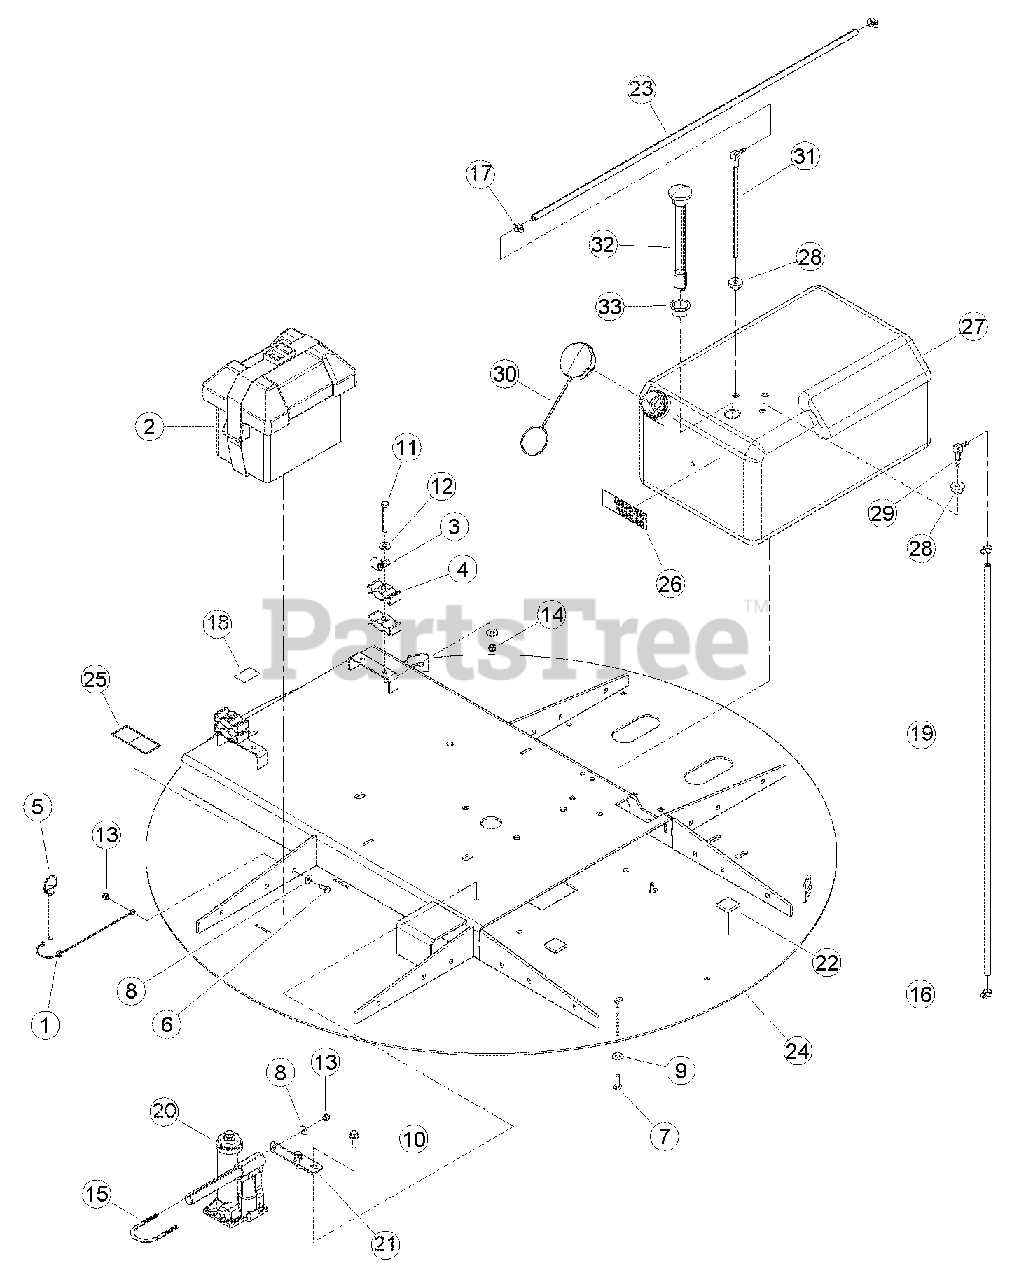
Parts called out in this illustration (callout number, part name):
1	LANYARD, NYLON
2	BOX, SMALL BATTERY
3	CLAMP, 9/16" COATED
4	CLAMP, PLASTIC HOSE
5	PIN, 3/8 HITCH
6	BOLT, 1/4 X 3/4 HEX HD GR5 ZP
7	BOLT, 3/8 X 3/4 HEX HD GR5 ZP
8	WASHER, 1/4 FLAT ZP
9	WASHER, 3/8 FLAT ZP
10	SCREW, 3/8-16 X 1 LG THD CUTT ZP
11	BOLT, 5/16 X 2-1/2 HEX HD GR5 ZP
12	WASHER, 5/16 FLAT ZP
13	NUT, 1/4 NE NYLOCK ZP
14	NUT, 5/16 NE NYLOCK ZP
15	U-BOLT, 1/4 X 1-1/2 PIPE
16	CLAMP, 15/32 SPRING
17	CLAMP, 9/16 SPRING
18	HOSE, 38" FUEL LINE
19	DECAL, P215/70R15 LOAD RATING
20	JACK, HYDRAULIC 2 TON
21	PLATE, JACK MOUNT
22	PAD, FOAM FUEL TANK DAMPER
23	HOSE, 28 INCH FUEL LINE 5/16"
24	ASSEMBLY, CHIPPER BASE, SERVICE PART
25	DECAL, LOCK
26	DECAL, UNLEADED GASOLINE
27	TANK, 9.5 GAL ROTOMOLDED FUEL
28	GROMMET, TANK FITTING
29	FITTING, TANK VENT
30	CAP, FUEL TANK VENTED
31	FITTING, TANK FUEL PICK-UP TUBE
32	GAUGE, FUEL LEVEL KELCH 100
33	GROMMET, KELCH 100 GAUGE
